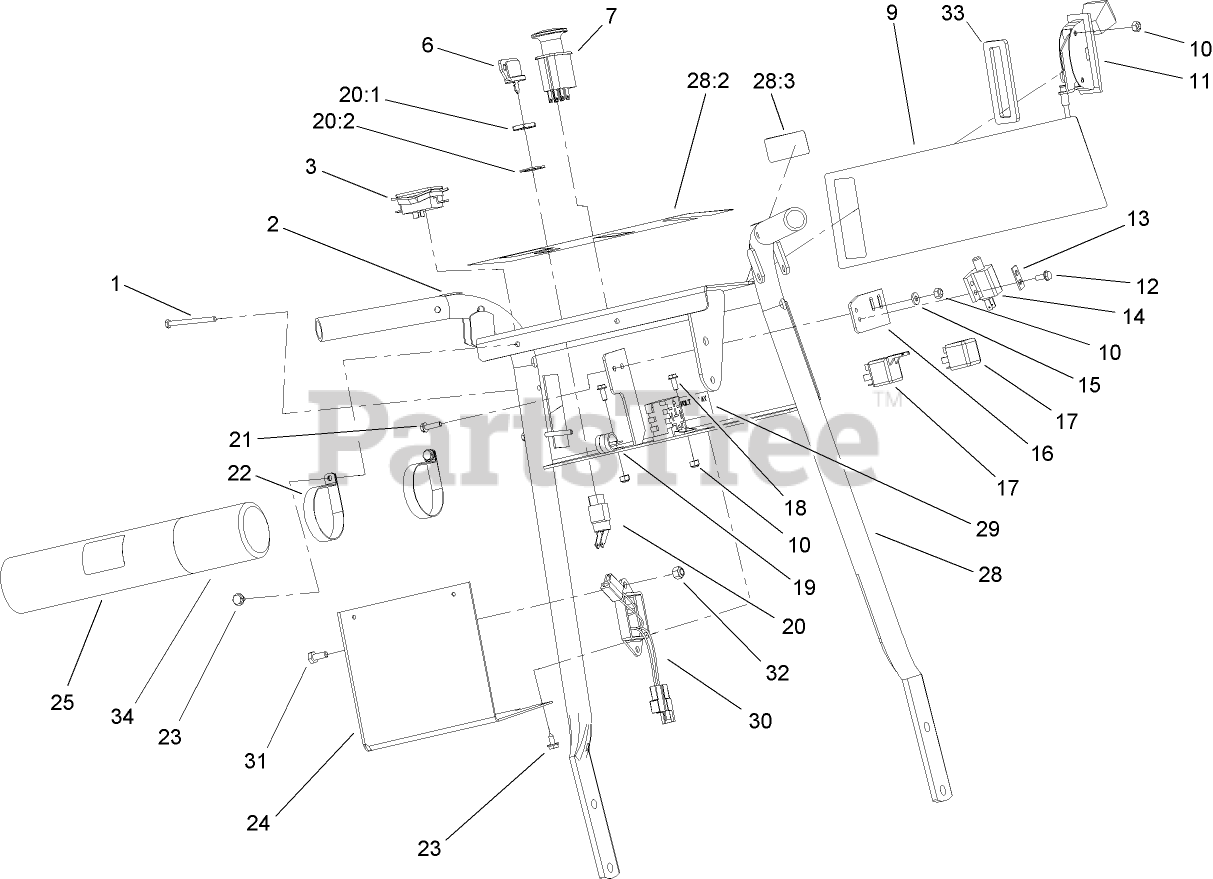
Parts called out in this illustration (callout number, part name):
1	SCREW-SHH
2	DECAL-LOCK, NEUTRAL
3	HOURMETER
6	KEY-IGNITION
7	SWITCH-PTO
9	DECAL-CONTROL, THROTTLE
10	NUT-LOCK, NI
11	CABLE-THROTTLE
12	SCREW-TAPTITE
13	PLATE-SWITCH
14	SWITCH-POLE, SINGLE
15	WASHER-FLAT
16	PLATE-MOUNTING, SWITCH
18	SCREW-HWH
19	CLAMP-R
20	SWITCH-ON / OFF
20:1	NUT-HH
20:2	WASHER-TOOTH, INTERNAL
21	SCREW-HWH
22	CLAMP-R
23	SCREW-HWHTF
24	BRACKET-COVER
25	TUBE-MANUAL
28	HANDLE ASM
28:2	DECAL-PANEL, CONTROL
28:3	DECAL-PROTECTION, EAR
29	DECAL-RELAY, 24 VOLT
30	Module-Filter
31	SCREW-HH
32	NUT-LOCK, NI
33	GASKET-THROTTLE
34	CAP-HOUSING
